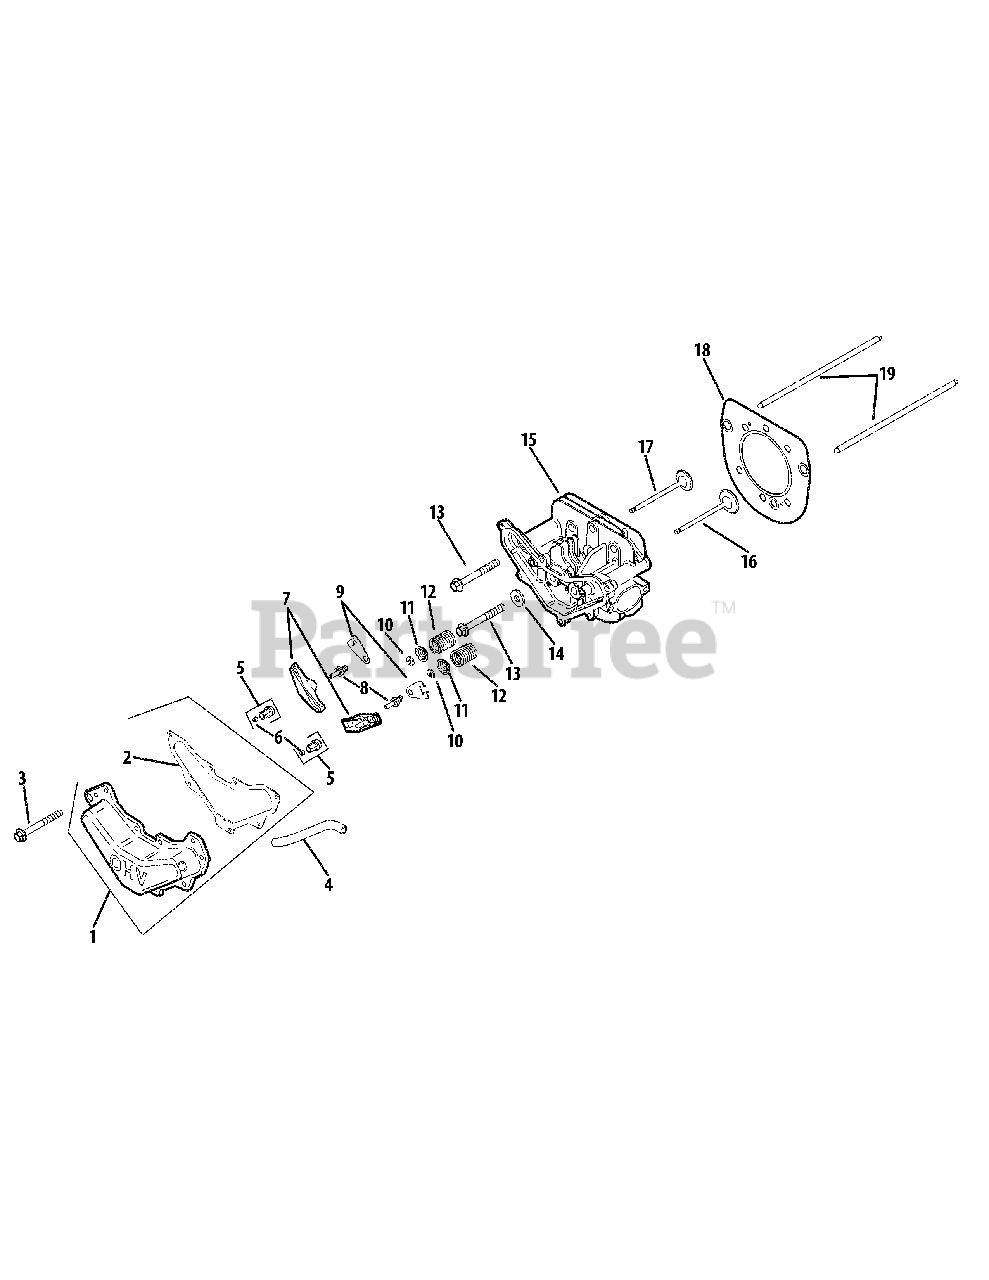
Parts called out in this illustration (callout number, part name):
1	Valve Cover Kit
2	Valve Cover Gasket
3	Flg Thd Frm Screw, M6 x 1.0 x 20
4	Breather Hose
5	Rocker Arm Pivot
9	Push Rod Guide Plate
10	Retainer Lock
11	Valve Spring Cap
13	Flg Screw, M10 x 1.5 x 80
14	Flat Washer, 13/32"
15	Cylinder Head Assembly
16	Exhaust Valve
18	Cylinder Hd. Gasket
19	Push Rod
